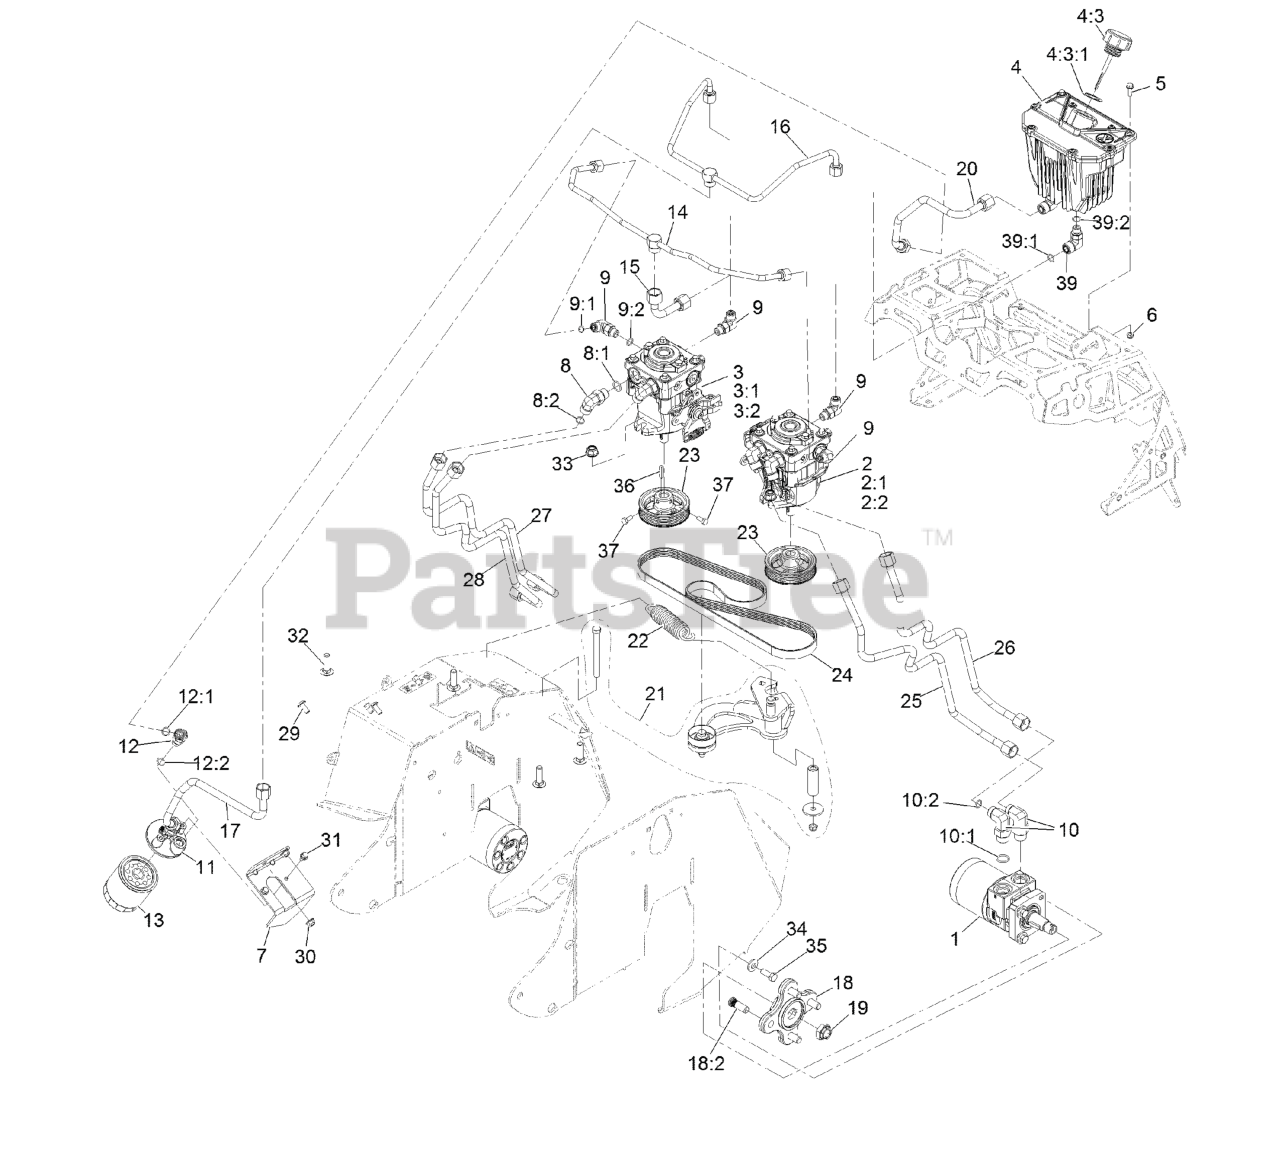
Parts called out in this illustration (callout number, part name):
1	Motor-Wheel
2	PUMP-HYDRAULIC 10CC
2:1	KIT, 10CC PUMP KIT
2:2	SEAL OVERHAUL KIT
3	PUMP-HYDRAULIC 10CC
3:1	KIT, 10CC PUMP KIT
3:2	SEAL OVERHAUL KIT
4	ASM, Hydraulic Reservoir
4:3	RESERVOIR CAP ASM
4:3:1	GASKET-CAP
5	SCREW-HWH
6	NUT-LOCK, NI
7	Bracket-Filter
8	FITTING-ELBOW, 90 DEG
8:1	O-RING
8:2	O-RING
9	FITTING-ELBOW, 90 DEG
9:1	O-RING
9:2	O-RING
10	FITTING-ELBOW, 90 DEG
10:1	O-RING
10:2	O-RING
11	HEAD-FILTER
12	Adapter
12:1	O-RING
12:2	O-RING
13	FILTER-25 MICRON, BI-DIRE
14	Line, Hydraulic, Case Tee
15	Line, Hydraulic, Case
16	Line, Hydraulic, Charge Tee
17	Line-Hydraulic Charge
18	ASM-Hub And Studs
18:2	STUD-WHEEL
19	NUT-LOCK
20	Line-Hydraulic Supply
21	ASM, Idler Arm
22	SPRING, EXTENSION
23	PULLEY, PUMP
24	Belt, Pvk5
25	Line-HYD Lt Rear
26	Line-HYD Lt Front
27	Line-HYD Rt Rear
28	Line-HYD Rt Front
29	SCREW-TORX
30	NUT-HF, NI
31	SCREW-HHF
32	BOLT-CARR
33	NUT-HF, NI
34	WASHER-BELLEVILLE
35	SCREW-HH
39	Fitting-HYD, 90 DEG
39:1	O-RING
39:2	O-RING
40	Washer-Thrust
